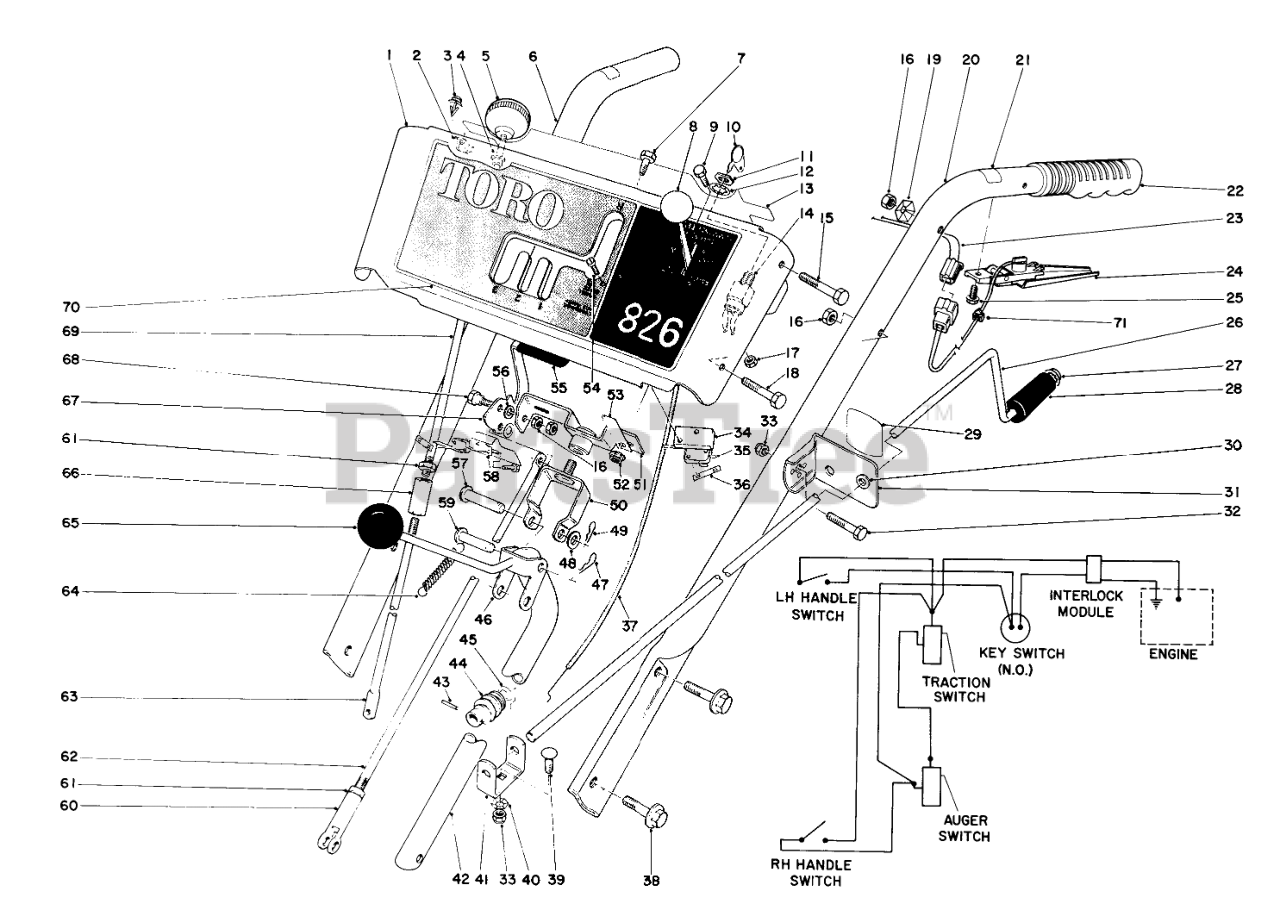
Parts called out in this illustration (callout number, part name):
1	Escutcheon Plate (Incl. Ref. #13 & 70)
2	WIRE CLAMP
3	Mounting Stud
4	NYLINER #6LI-FF TYPE 7
5	KNOB-LEVER
6	Handle Right
7	SCREW-HH
8	CONTROL KNOB
9	HEX HEAD SEMS 10-24X1/2
10	Key
11	NUT-HH
12	WASHER-TOOTH, INTERNAL
13	BACK ESCUTCH DECAL
14	Key Switch (Incl. Ref. #11 & 12)
15	SCREW-HH
16	NUT-LOCK, CONE
17	NUT-LOCK, NI
18	SCREW-HH
19	Washer
20	HANDLE LEFT
21	INTERLOCK DECAL
22	Grip Handle
23	WIRE HARNESS INTERLOC
24	Interlock Handle & Switch (Incl. Ref. #71)
25	SCREW
26	Chute Control Rod
27	RETAINER-PUSH ON
28	GRIP-CONTROL, CHUTE
29	CHUTE DECAL
30	Bushing
31	Bracket-Chute Control (Incl. Ref. #29 & 30)
32	SCREW-HH
33	NUT-LOCK, NI
34	SWITCH MTG PAD
35	SWITCH-MICRO
36	NUT-SPEED
37	Throttle Contrl
38	SCREW-HHF
39	BOLT-CARR
40	WASHER-LOCK
41	WORM BRACKET
42	Rod Traction Shift
43	PIN-SPRING
44	GEAR-WORM, CHUTE
45	WASHER-SPRING
46	SHIFT ROD WA
47	PIN-COTTER
48	WASHER-FLAT
49	PIN-HAIR
50	PIVOT BRKT WA
51	SWIVEL BLOCK WA
52	NUT-LOCK, HHF
53	Retainer Wire
54	SCREW-SPH
55	AUGER CLUTCH HND GRIP
56	WASHER-PLAIN
57	PIN-CLEVIS
58	SWITCH BRKT
59	PIN-CLEVIS
60	CLEVIS
61	NUT-HJ
62	DRAG LINK
63	Rod-Wheel Clutch, Lower
64	CONT ROD SPRING 0
66	WHL ROD COUPLING
67	Auger Clutch Handle
68	SCREW-SHOULDER
69	UP WHEEL CLUTCH ROD
70	ESCUTCHEON DECAL
71	Mount-Wire
